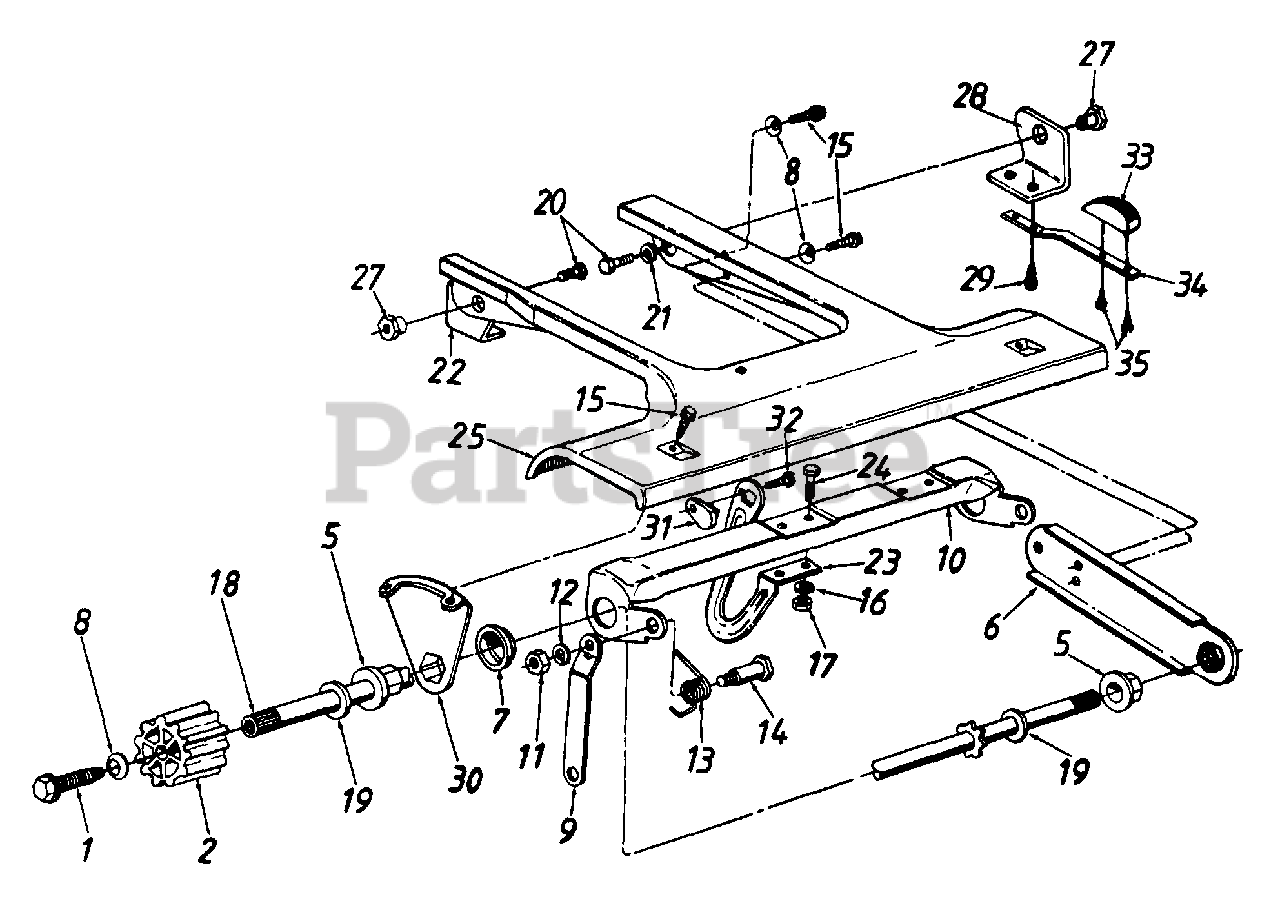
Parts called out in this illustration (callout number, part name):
1	Hex Scr. 1/4-20 x .75" Lg. (Gr. 5)
2	Wheel Drive Pinion
5	Hex Flange Brg .504" I.D.
8	Bell-Wash .265" I.D. x .75" O.D.
11	Hex Nut 5/16-18 Thd.
12	L-Wash. 5/16" I.D.
13	Torsion Spring - R.H.
14	Shoulder Bolt .437" Dia.
15	Hex Wash. Hd. AB-Tap Scr. 1/4 x .62" Lg.
16	L-Wash. 1/4" I.D.
17	Hex Nut 1/4-20 Thd.
18	Drive Shaft Ass'y.
19	Fl-Wash .531" I.D. x .93" O.D.
20	Hex Bolt 3/8-16 x .5" Lg
21	L-Wash. 3/8" I.D
32	Hex B-Tap Scr. #10 x 44" Lg.
33	Chain Tensioner
34	Cantilever Spring
35	Hex B-Tap Scr. #10 x 38" Lg
